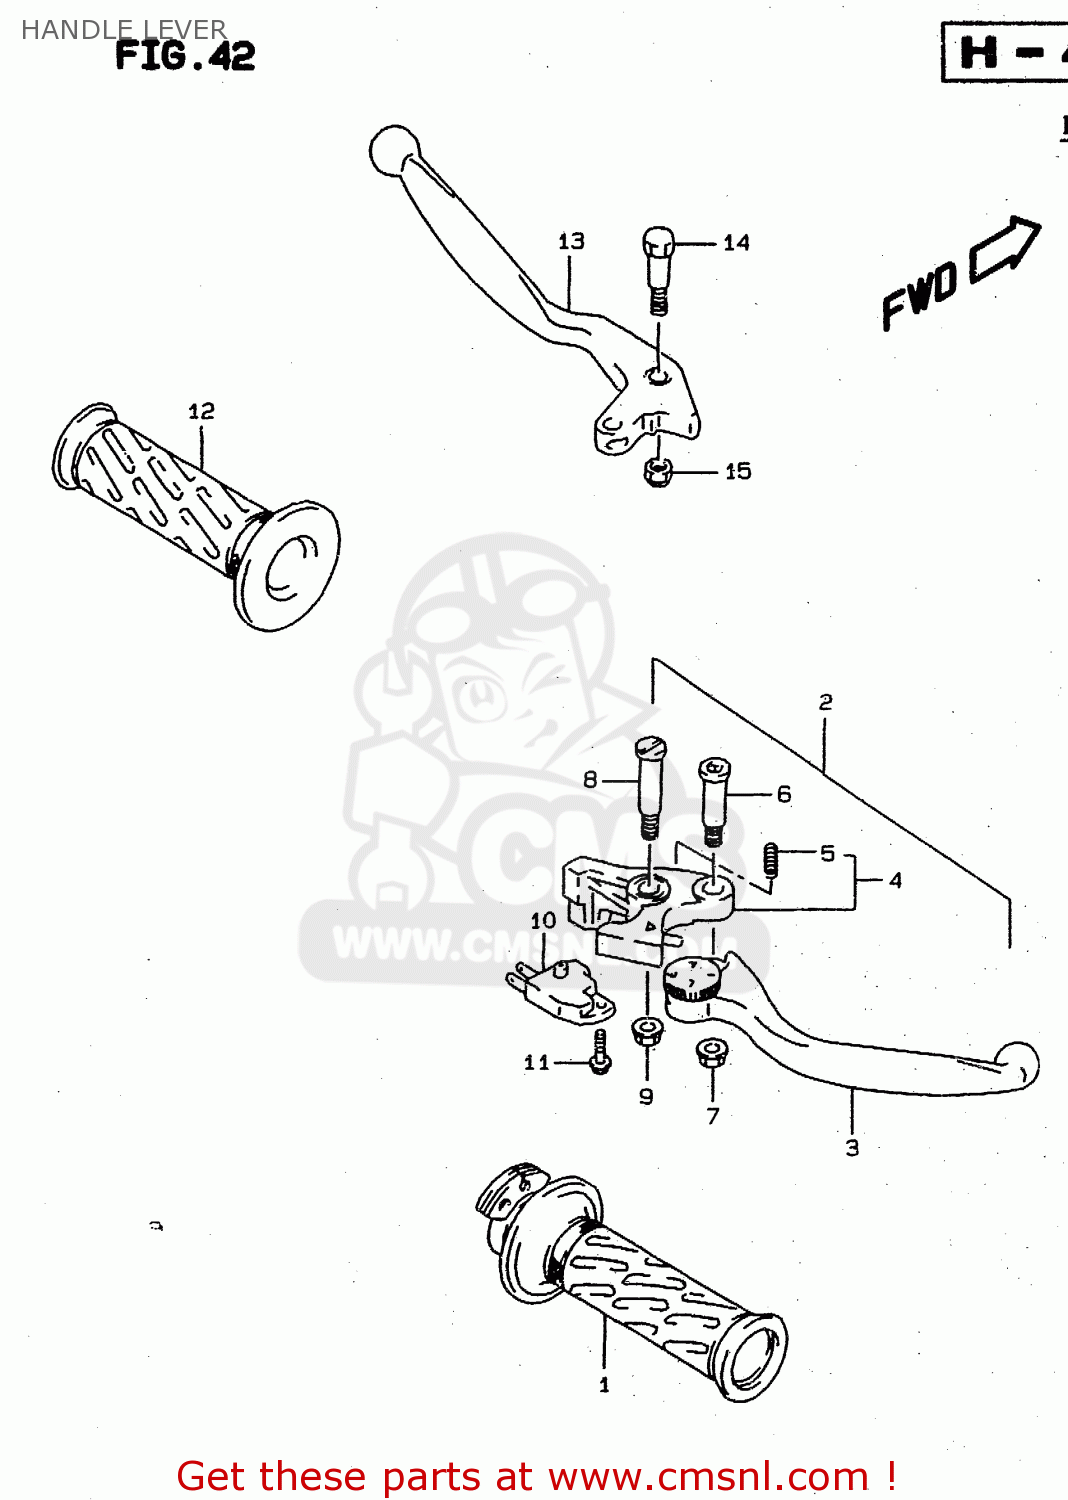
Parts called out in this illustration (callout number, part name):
1	GRIP,THROTTLE
2	LEVER ASSY,BRAKE
3	LEVER,ADJUST
4	KNOCKER
5	SPRING
6	BOLT,LEVER
7	NUT
8	BOLT,LEVER PIVOT
9	NUT
10	SWITCH ASSEMBLY,STOP
11	SCREW
12	GRIP,LEFT
13	LEVER,CLUTCH (SILVER)
14	BOLT,LEVER
15	NUT
